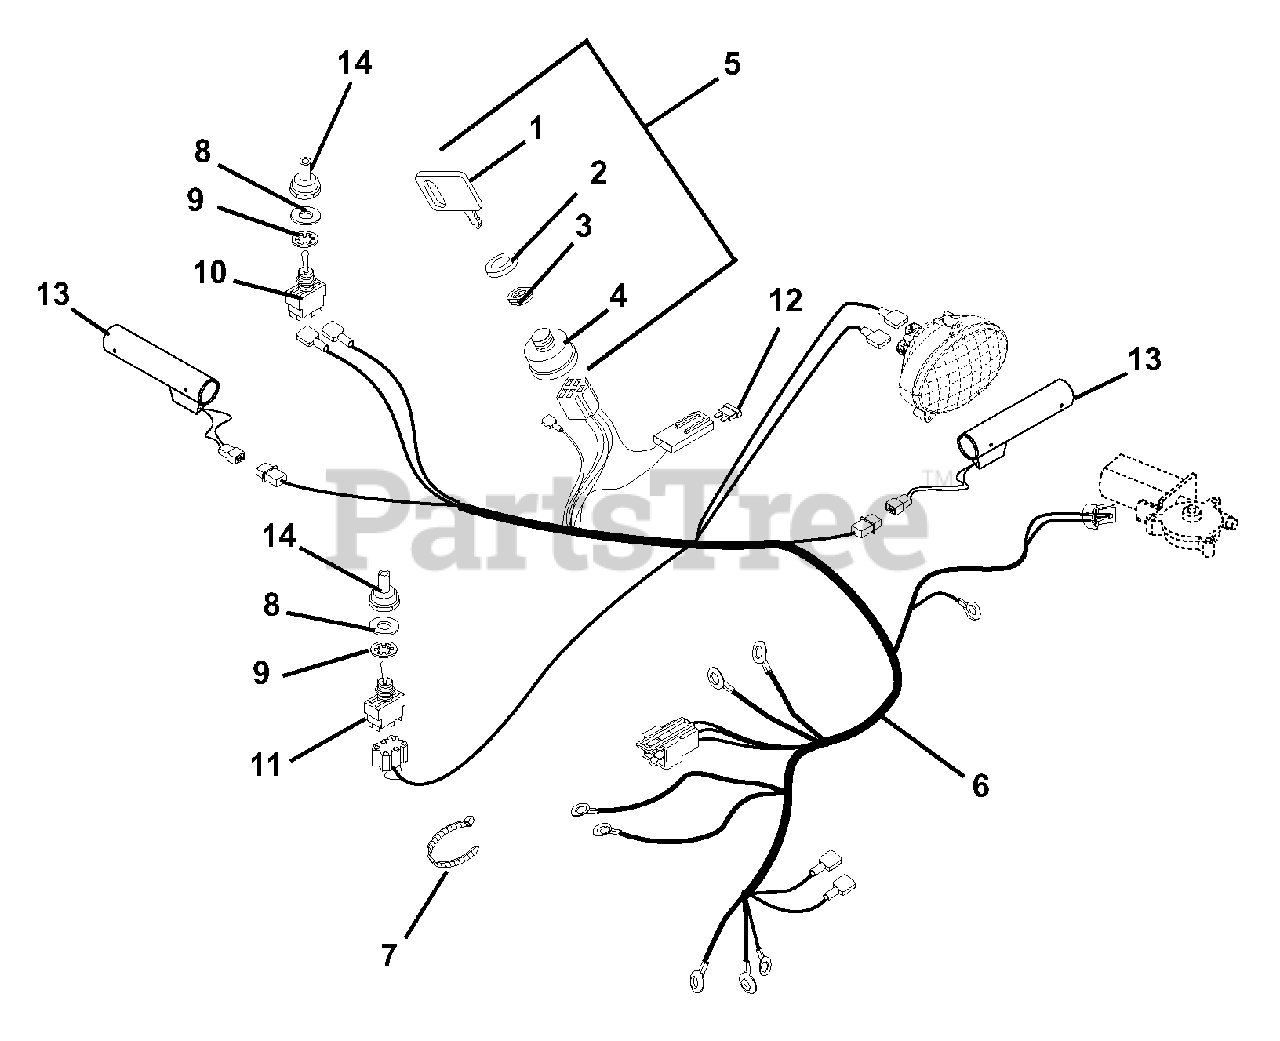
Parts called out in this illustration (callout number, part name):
1	KEY -W/CAP
2	CAP - IGNITION SWITCH
3	NUT-PANEL .625-32 GRECO
4	IGNITION SWITCH ASSEMBLY
5	SWITCH ASSEMBLY
6	HARNESS, WIRE-LIGHT,HANDWARMER
6	HARNESS, WIRE - LT,HW,12V
6	HARNESS, WIRE-LT,HW,12V,CHUTE
7	CABLE TIE LG 5-1/2
8	WSHR-FL-STL .505X.875X.024 PL
9	WSHR-LK-INT .563X.040 YWZC
10	SWITCH, ON/OFF
11	SWITCH, CHUTE ROTATION
12	FUSE, 15 AMP.
13	WARMER, HAND W/TERMINAL
14	BOOT, SWITCH
